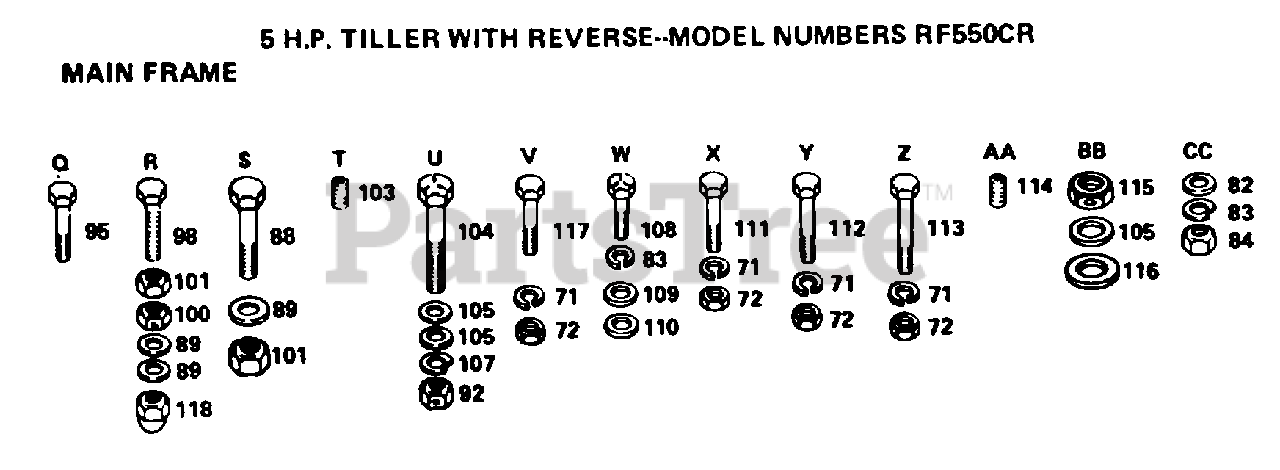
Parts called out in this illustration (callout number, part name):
71	LOCKWASHER
72	NUT.HEX.5/16-18
82	WASHER
83	LOCKWASHER
89	WASHER
92	GRIPCO NUT
101	NUT.HEX.3/8-16UNC
103	SET SCREW
104	BOLT.3/8-24X3.75
105	WASHER
107	LOCKWASHER
108	BOLT
109	WASHER
110	WASHER
111	BOLT
114	SET SCREW
117	BOLT.HEX.5/16-1.5
